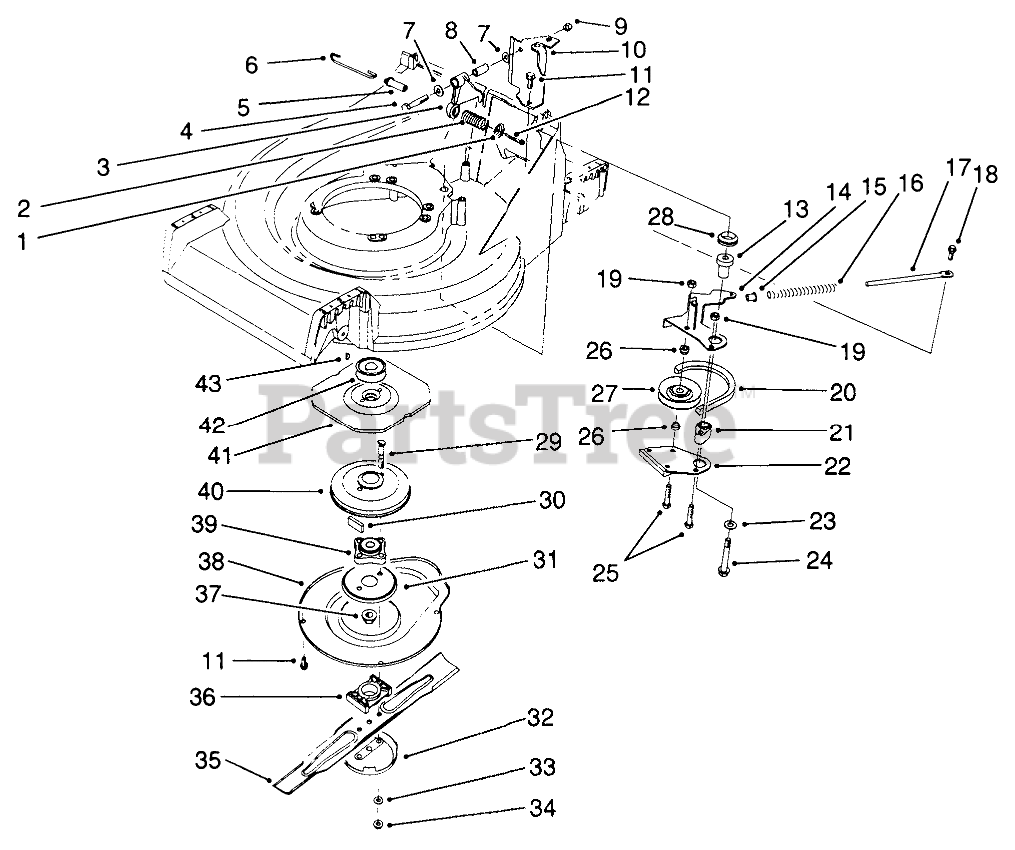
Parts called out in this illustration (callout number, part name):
1	RETAINER-SPRING
2	COMPRESSION SPRING
3	CRANK
4	SCREW-HH
5	SPRING PIN
6	CONTROL LINK
7	WASHER-PLAIN
8	STRAIGHT BUSHING
10	Bracket-Cable Support
11	SCREW-HWHTF
12	SCREW-HWHTF
13	BBC PM BUSHING
14	Lever
15	SPACER
16	COMPRESSION SPRING
17	SPRING ROD
18	SCREW-SHOULDER
19	NUT-LOCK, NI
20	V-BELT
21	BRAKE PLATE HUB
22	BRAKE SHOE
23	WASHER-PLAIN
24	3/8-16 X 2-3/4 CAPSCR
25	SCREW-HH
26	IDLER PULLEY HUB
27	PULLEY-IDLER
28	V-RING SEAL
29	BOLT-BLADE
30	DAMPENER-VIBRATION
31	Screen-BBC
32	Anti Scalp Cup
33	WASHER
34	NUT-LOCK
35	Key
36	SPACER-BLADE
37	NUT-LOCK, NI
38	Cover
39	HUB ASM
40	BRAKE DRUM
41	FLYWHEEL - BBC
42	PULLEY
43	KEY-WOODRUFF
